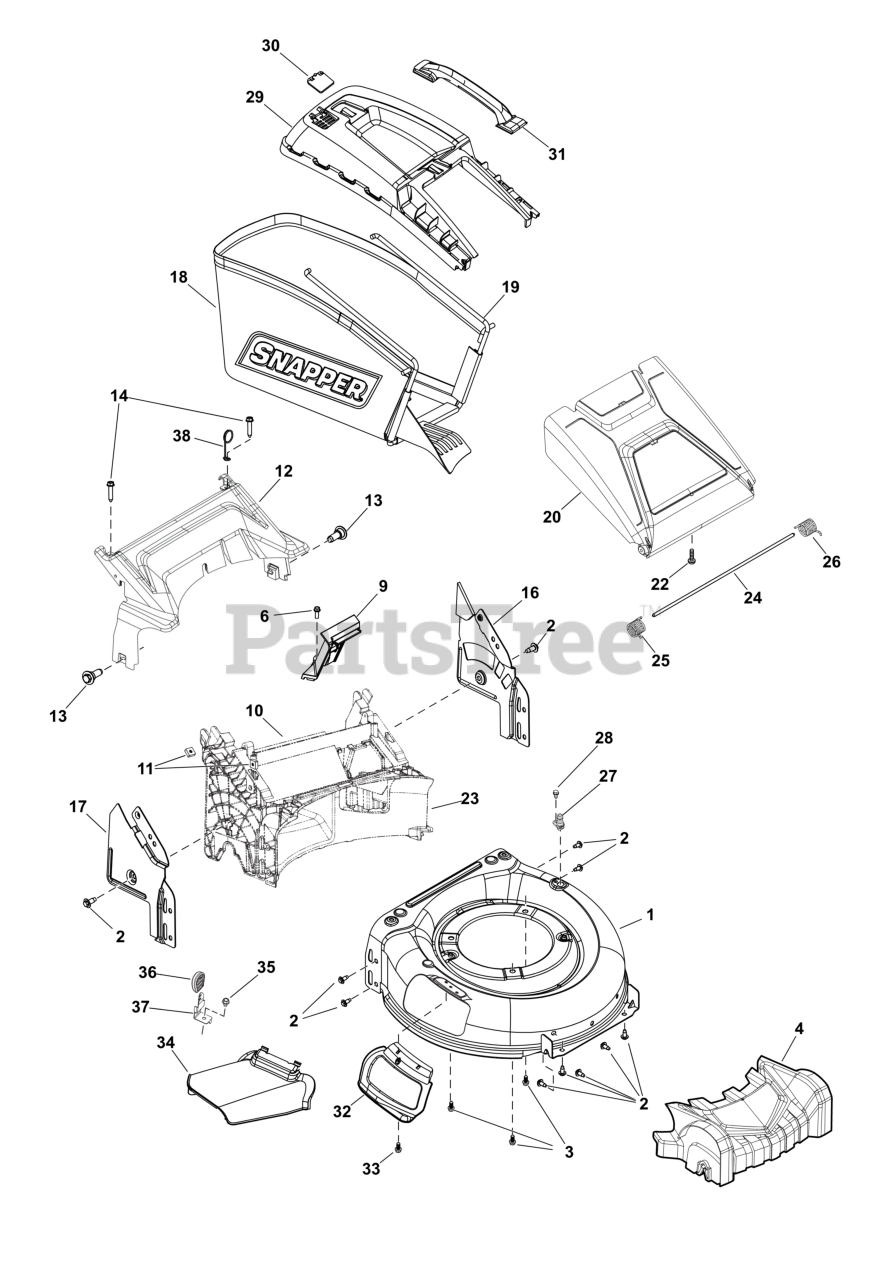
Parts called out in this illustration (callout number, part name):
1	DECK, NSP
2	SCREW, 8mm
3	SCREW, Engine Mounting, 3/8-16 x 1
4	FRONT COVER, Deck
6	HWST, 1/4-15X3/4 BZ
9	COVER, Rear
11	LOCKNUT, Square
12	COVER, Rear
13	BOLT, Shoulder, 5/16-14 x .972
14	SCREW, 1/4-15 x 1-1/4
16	SUPPORT, Handle, LH
17	SUPPORT, Handle, RH
20	REAR FLAP
22	SCREW #10-16 x 3/4
25	TORSION SPRING, RH
26	TORSION SPRING, LH
27	NOZZLE, Wash
28	SCREW, 1/4-20 x 1/2
29	COVER, Bagger
30	INDICATOR, Full Bag
32	MULCHING FLAP
33	CAPSCREW, 1/4-20 X 1/2
34	DEFLECTOR
35	CAPSCREW, 1/4-20 X 3/8
36	KNOB, Adjustment Lever
37	LEVER, Adjustment
38	GUIDE, Cable
